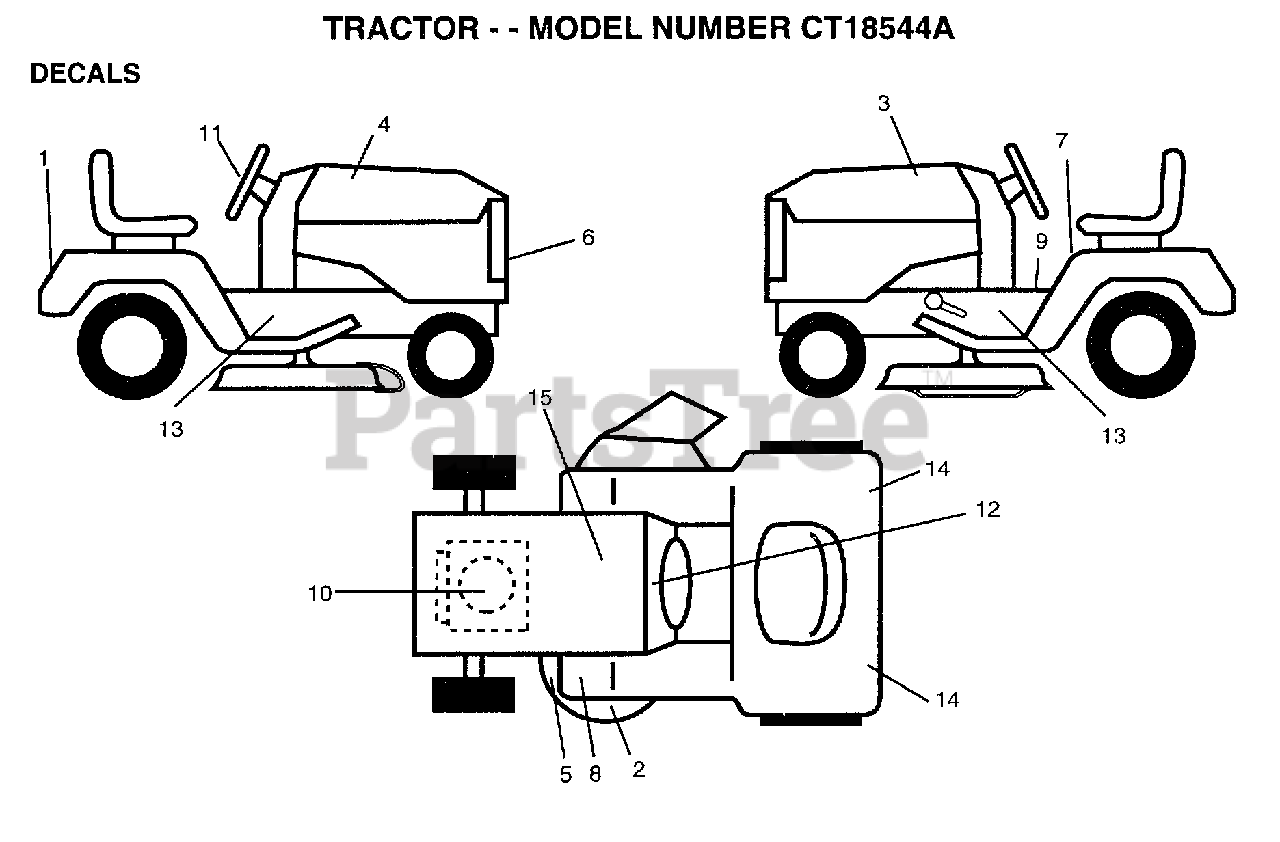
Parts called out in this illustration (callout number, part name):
1	DECAL.FEND.RALLY
2	"DECAL, WARNING"
3	DECAL HOOD LH
4	"DECAL,HOOD RH"
5	"DECAL.V.BELT.44"""
6	DECAL, GRILLE
7	DECAL
9	DECAL.HOOD.INSERT
9	DECAL BRAK PARK
10	DECAL, HP, ENGINE
11	DECAL.WHL.STR.RLY
12	DECAL.DASH.INST.
13	DECAL CHASSIS 6SP
14	REFLECTOR-TAIL YT
15	DECAL.BTRY.DANGER
